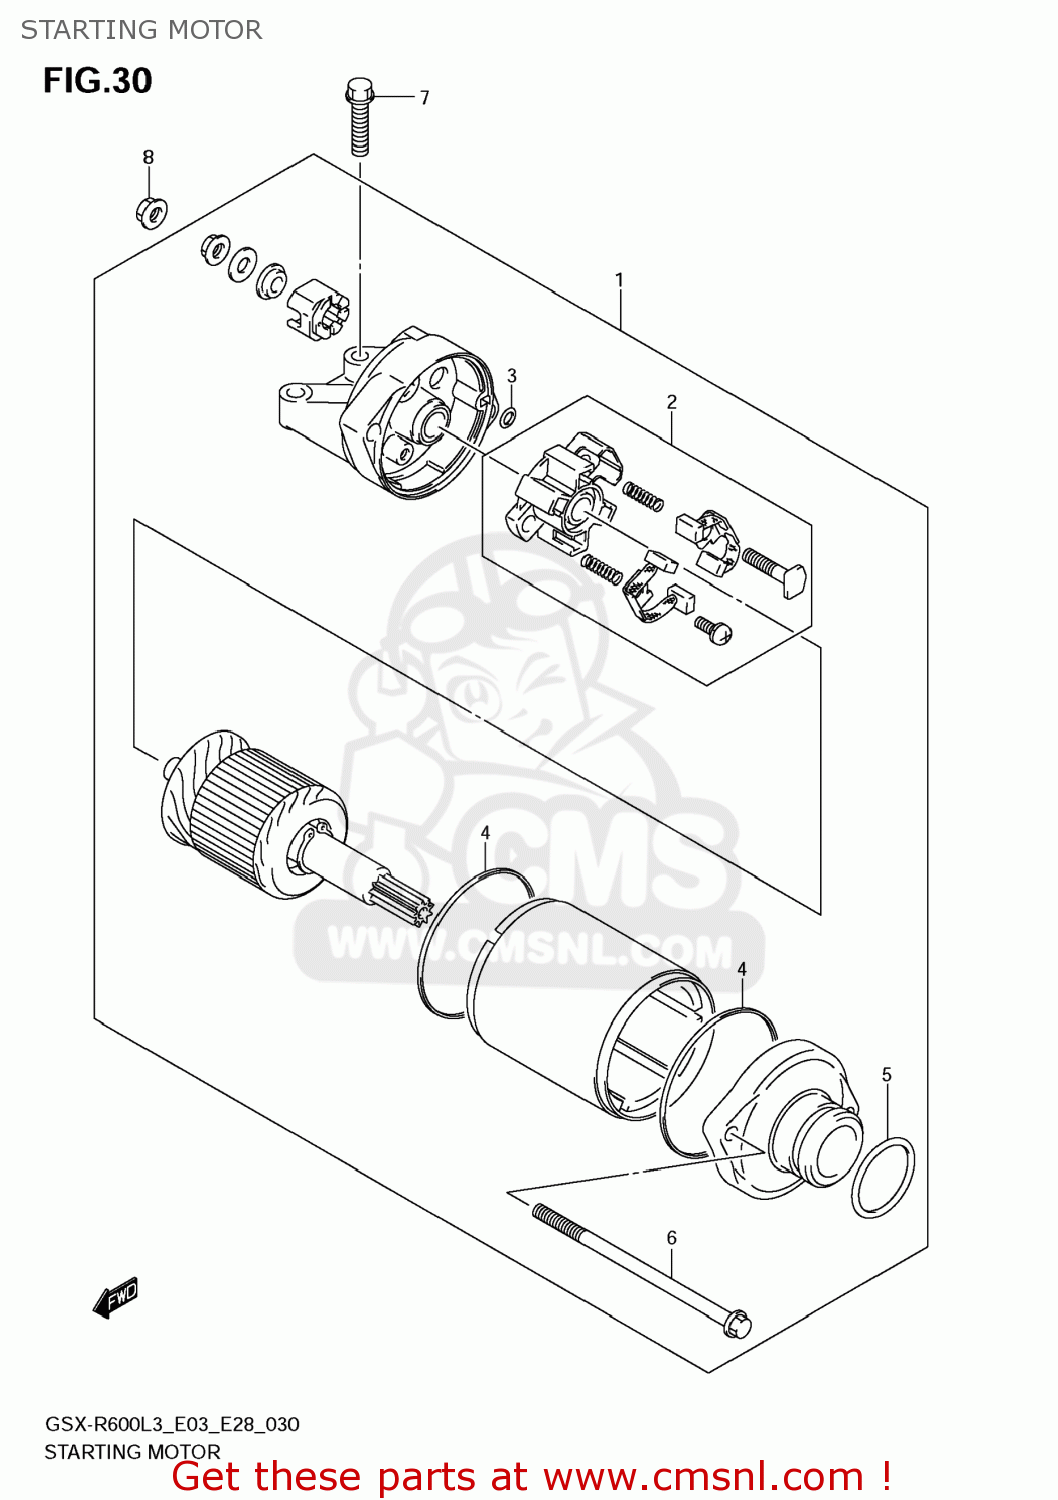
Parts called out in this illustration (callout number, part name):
1	MOTOR ASSY,STARTING
2	BRUSH HOLDER SET
3	O RING
4	SQUARE RING
5	O RING
6	BOLT
7	BOLT(6X25)
8	NUT
